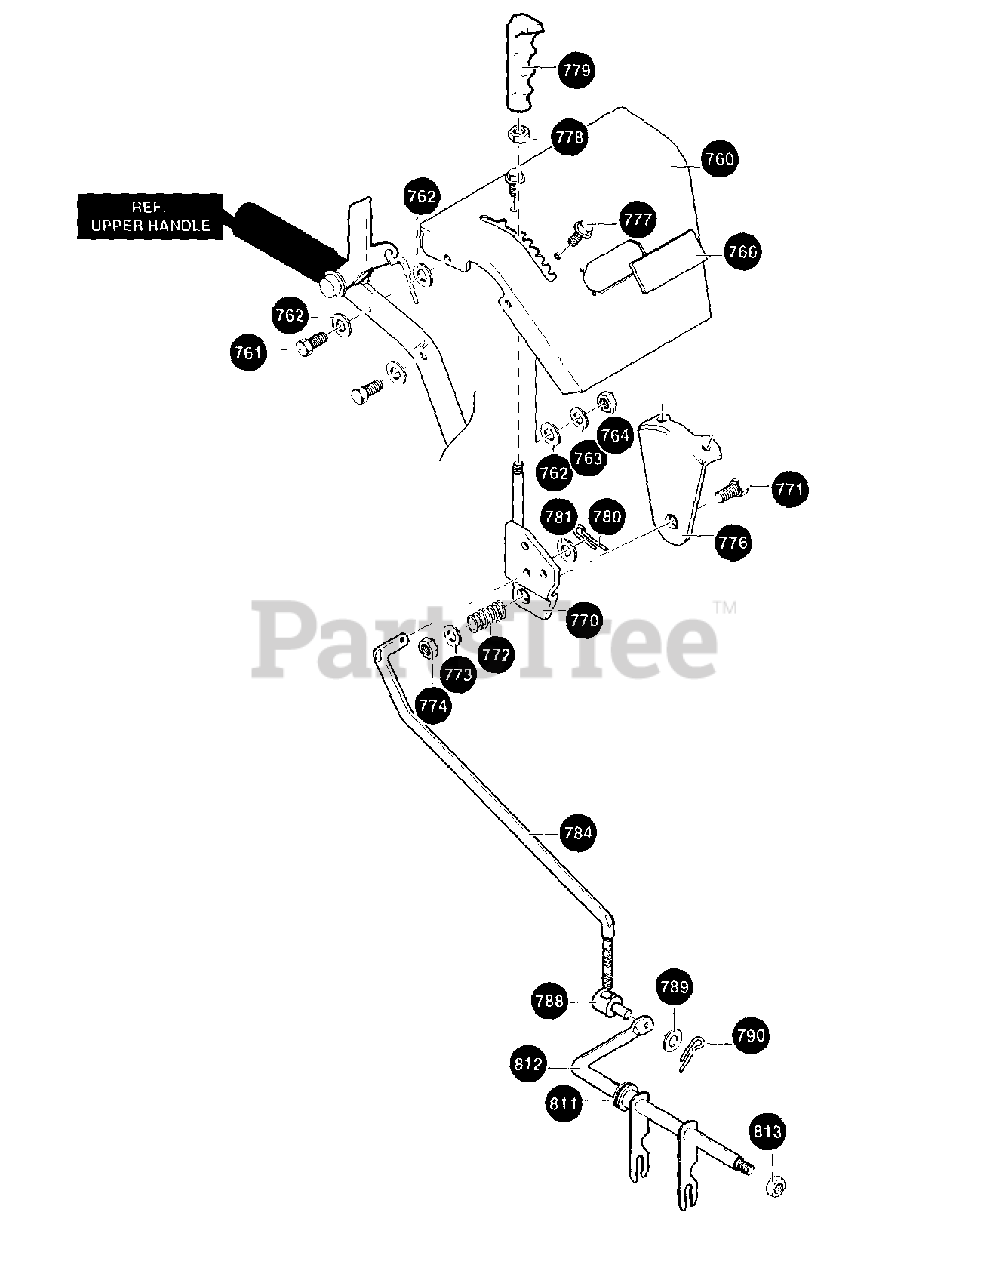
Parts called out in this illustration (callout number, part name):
760	PANEL,CONTROL
761	SCREW, 5/16-18 X 1.75
762	FLATWASHER .344 X .69 X .065
763	WASHER, .328 X .60 X .09
764	NUT, 5/16-18 REGHEX
766	PLATE, PANEL
770	HANDLE, ASSY
771	SCREW, 3/8-16 X 2.00
773	FLATWASHER .406 X .81 X .065
774	NUT, 3/8-16
777	SCREW, 5/16 18 X .50
778	NUT, 3/8-16
779	HANDLE 3/8-16
780	PIN, COTTER
781	WASHER, FLAT
784	ROD, SPEED CONTROL
788	NUT, TRUNNION
789	FLATWASHER .344 X .69 X .065
790	PIN, COTTER
811	BEARING, FLANGE
813	NUT, 3/8-16
